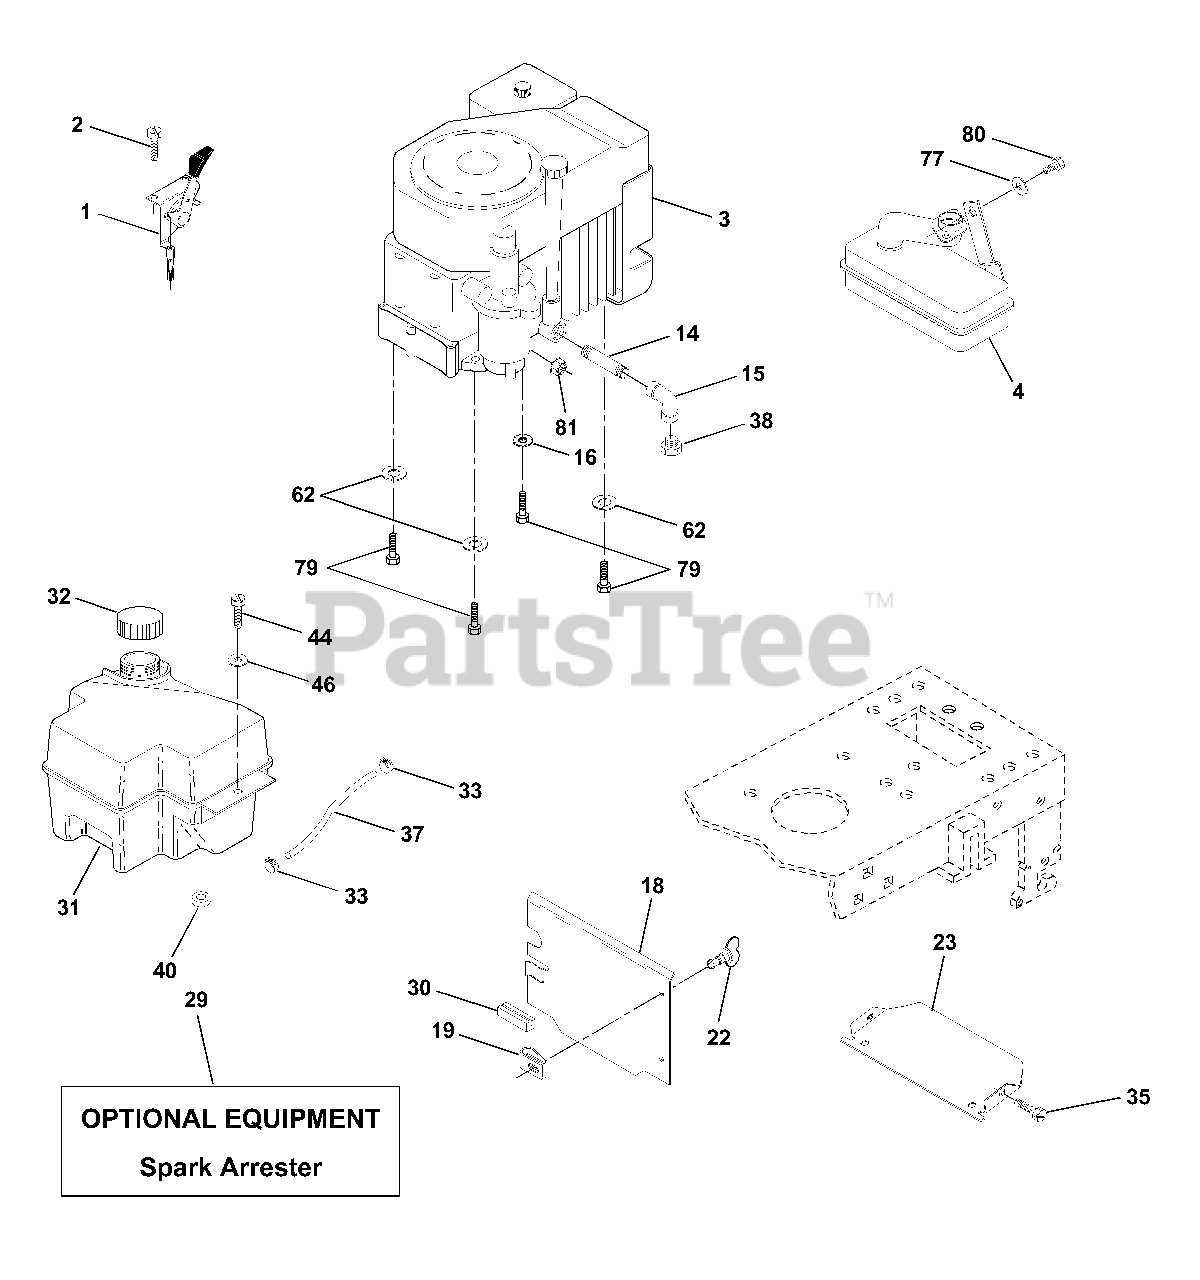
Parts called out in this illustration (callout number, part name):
1	Control THTICH 27 LH FIAG DOM
2	Screw Hex Thd Cut 1/4-20x5/8 T
3	Engine Kohler, Model Number CV15S 13 HP
4	Muffler LT Koh 12.5/15HD
14	Nipple Pipe 3/8 Npt X 3-1/2
15	Elbow Std 90 Degree 3/8-18 Npt
16	Washer Lock Ext Tooth 5/16
18	Shield Heat Lt
19	Receptacle 1/4 turn
22	Stud 1/4 turn
23	Shield Heat Browning LT/YT
29	Kit Spark Arrestor (Flat Scrn)
30	Pinch Weld Hood Black
31	Tank Fuel Front 2 00
32	Cap Asm Fuel W/sym Vented
33	Clamp Hose Black
35	Screw Thdrol 5/16-18 x 3/4 Tyt
37	Line Fuel 20"
38	Plug Oil Drain
40	Bushing Snap Nyl Blk Fuel Line
44	Screw Hexwsh Thdrol 1/4-20x3/4
46	Washer 9/32 X 7/8 X 16 Ga
62	Washer Lock Hvy Hlcl Spr 5/16
77	Washer 5/16 x 3/4 x 16 Ga.
79	Bolt Hex
80	Bolt Hex Hd 5/16-18 UNC x 1/2
81	Nut Flange 1/4-20 Starter Nut
